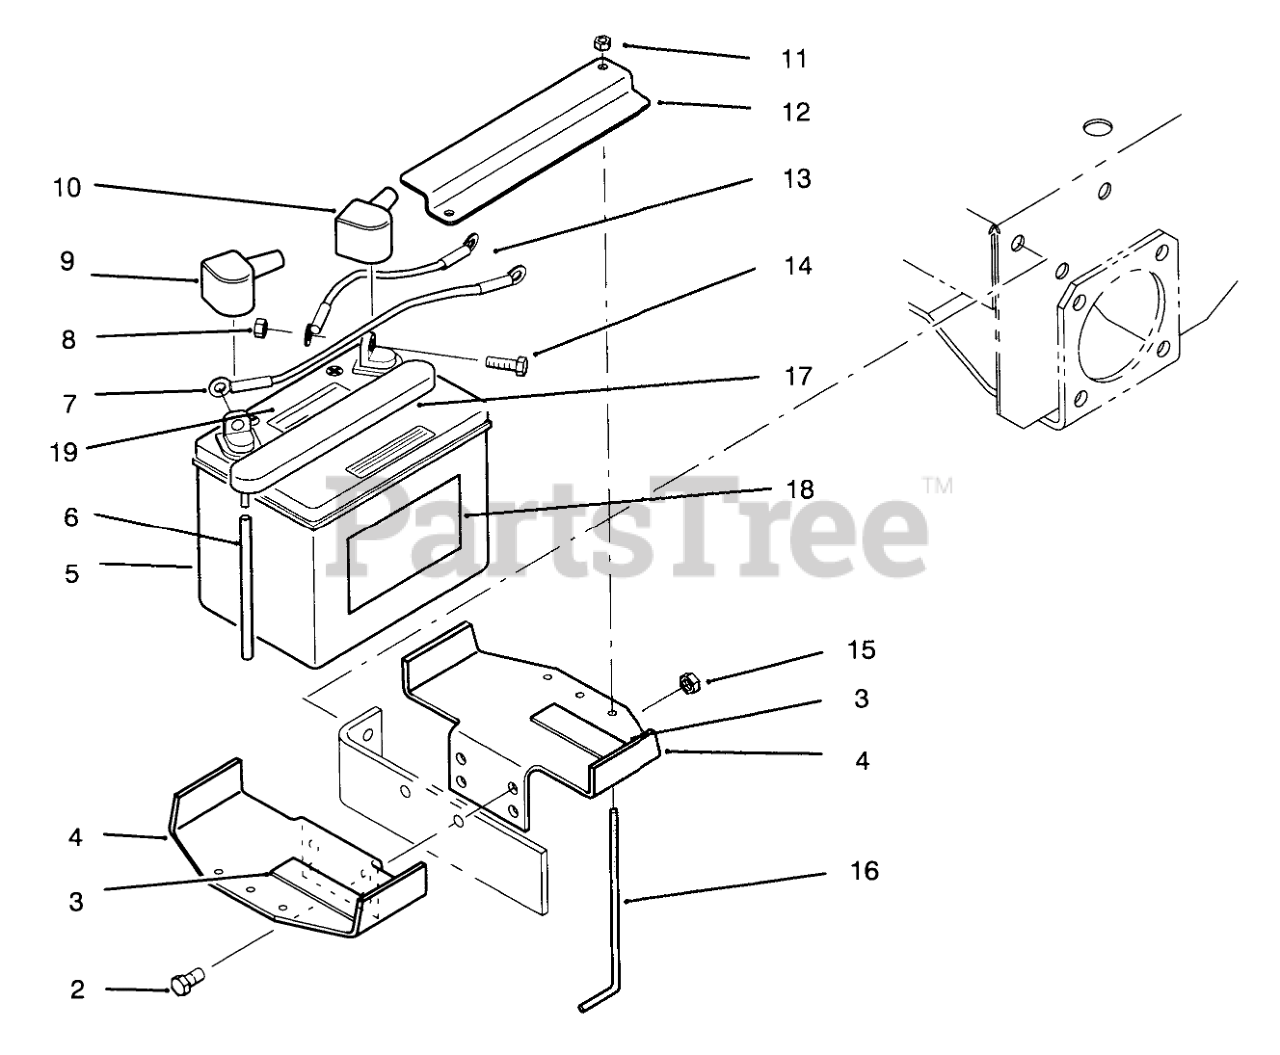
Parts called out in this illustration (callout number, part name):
2	SCREW-HH
3	PAD-TANK, FUEL
4	Battery
5	Battery
6	TUBE-VENT
7	WIRE ASM
8	NUT-KEPS
9	BOOT-TERMINAL, BLACK
10	BOOT-TERMINAL, RED
11	NUT-LOCK, NI
12	Clamp-Battery
13	WIRE ASM
14	SCREW-HH
15	NUT-LOCK, NI
16	ROD-SUPPORT, BATTERY
18	DECAL-BATTERY
19	DECAL-DANGER
